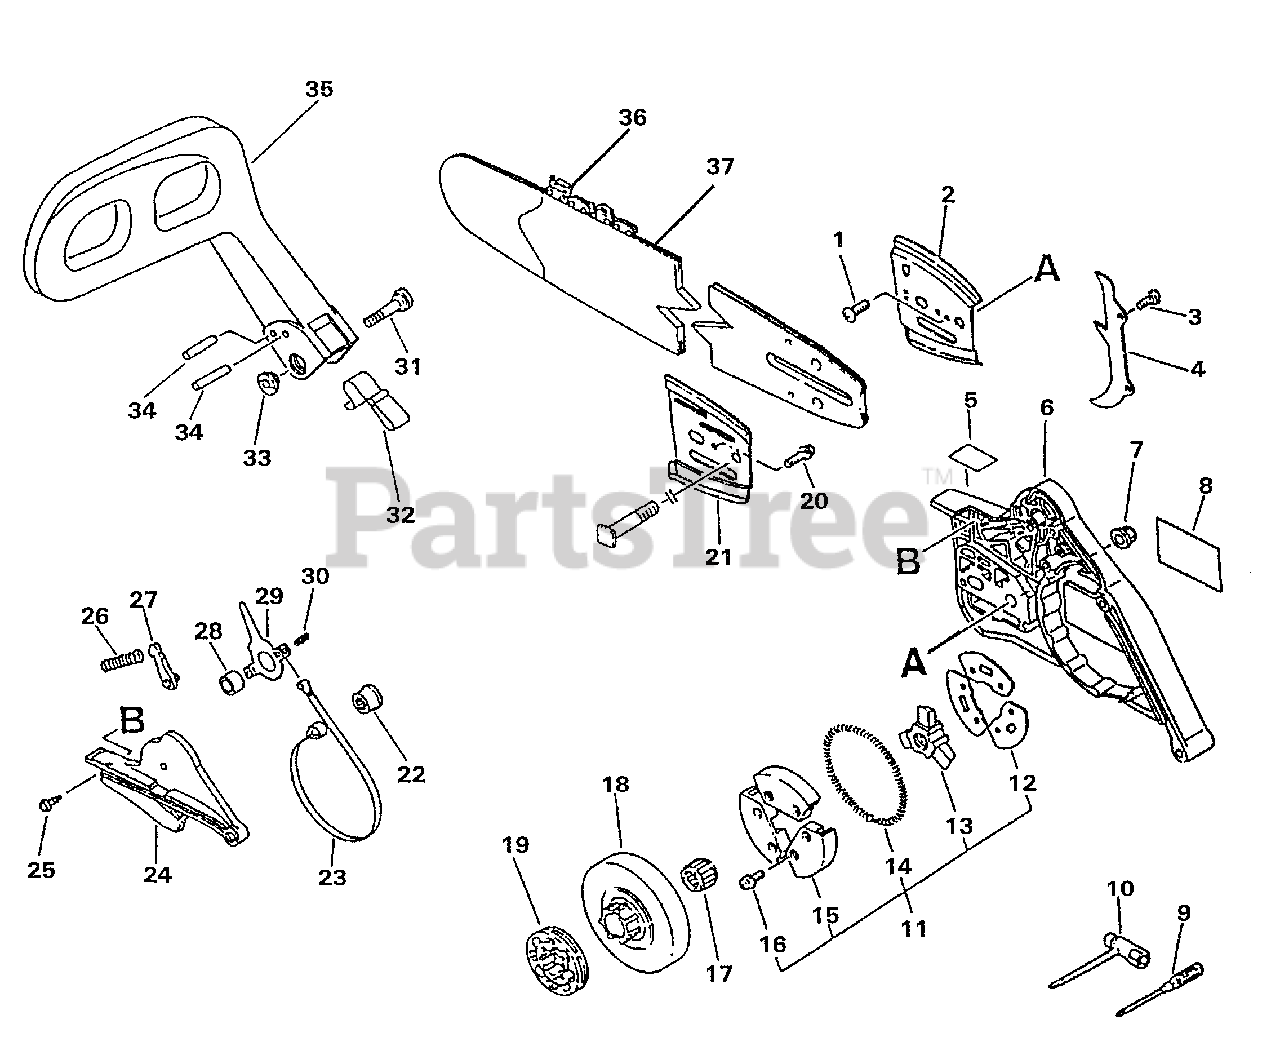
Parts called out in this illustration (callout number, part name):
1	SCREW 4×8
2	PLATE, GUIDE
3	SPIKE KIT, BUMPER
5	LABEL, CAUTION
6	GUARD, SPROCKET
7	NUT, FLANGE M8×1.25
8	LABEL, ECHO
9	SCREWDRIVER, PHILLIPS
10	T-WRENCH 13×19×180
11	CLUTCH ASSY
12	PLATE, CLUTCH
13	HUB, CLUTCH
14	SPRING, CLUTCH
15	SHOE SET, CLUTCH (3PCS)
16	BOLT 4×6
17	BEARING, NEEDLE
18	DRUM, CLUTCH
19	SPROCKET, 0.325 RIM
20	SCREW 3×6
21	PLATE, GUIDE - INNER
22	ADJUSTER, BRAKE
23	BAND, BRAKE
24	COVER, BRAKE
25	SCREW 4×10
26	SPRING, COMPRESSION
27	STOPPER, BRAKE
28	SPACER 8×12×9
29	LEVER, BRAKE
30	PIN, SPRING 4×8.8
31	MOUNTING KIT
32	SPRING, RETURN
34	PIN 3.5×26
35	LEVER, BRAKE
36	SAWING CHAIN - 16" -- PRO GUARD
36	SAWING CHAIN - 18" -- PRO GUARD
36	SAWING CHAIN - 20" -- PRO GUARD
37	GUIDE BAR - 16" -- DOUBLE GUARD
37	GUIDE BAR - 18" -- DOUBLE GUARD
37	GUIDE BAR - 20" -- DOUBLE GUARD
